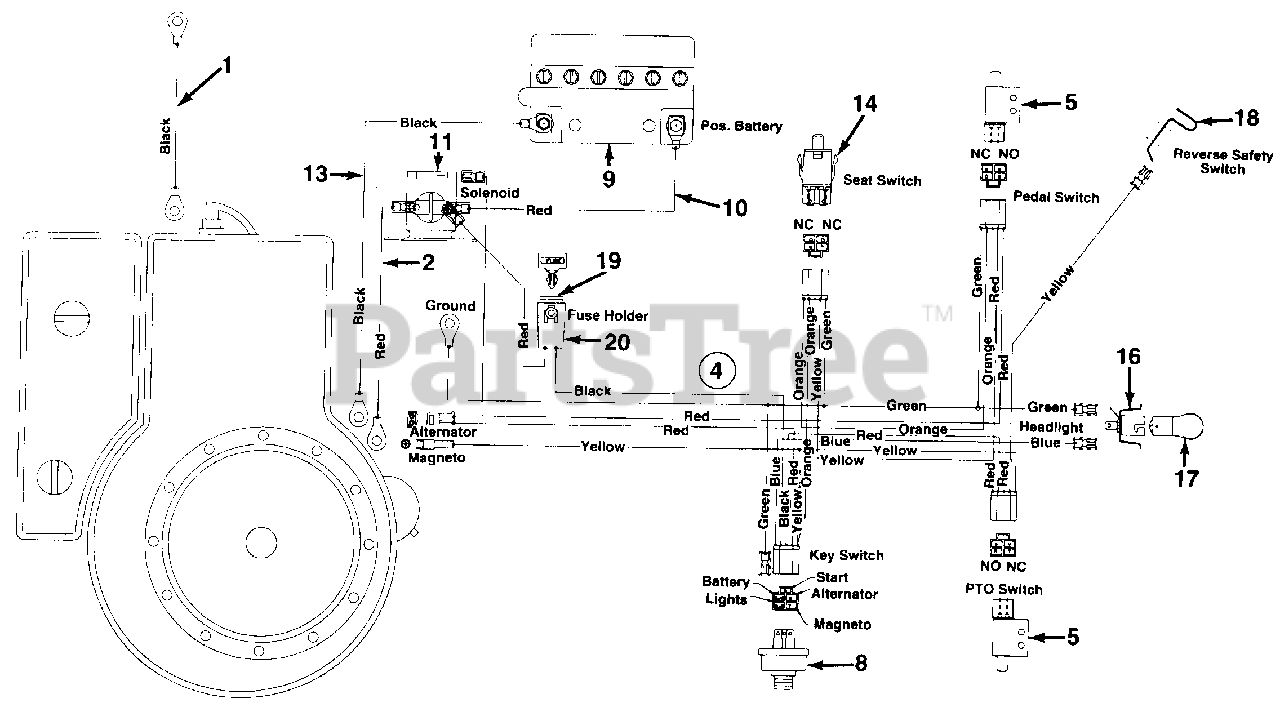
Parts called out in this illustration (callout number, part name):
1	Elec. Wire 8 Ga. x 11.5" Lg. (Black)
2	Elec. Wire 8 Ga. x 15.5" Lg. (Red)
4	Wire Harness
5	Safety Switch
8	Ignition Switch
9	Battery 12V
10	Elec. Wire 8 Ga. x 22" Lg. (Red w/Boot)
11	Solenoid
13	Elec. Wire 8 Ga. x 17" Lg. (Black)
14	Seat Switch
16	Headlight Socket
17	Lamp
18	Safety Switch
19	Fuse, Automotive Type 7 1/2 Amp.
20	Fuse Holder
